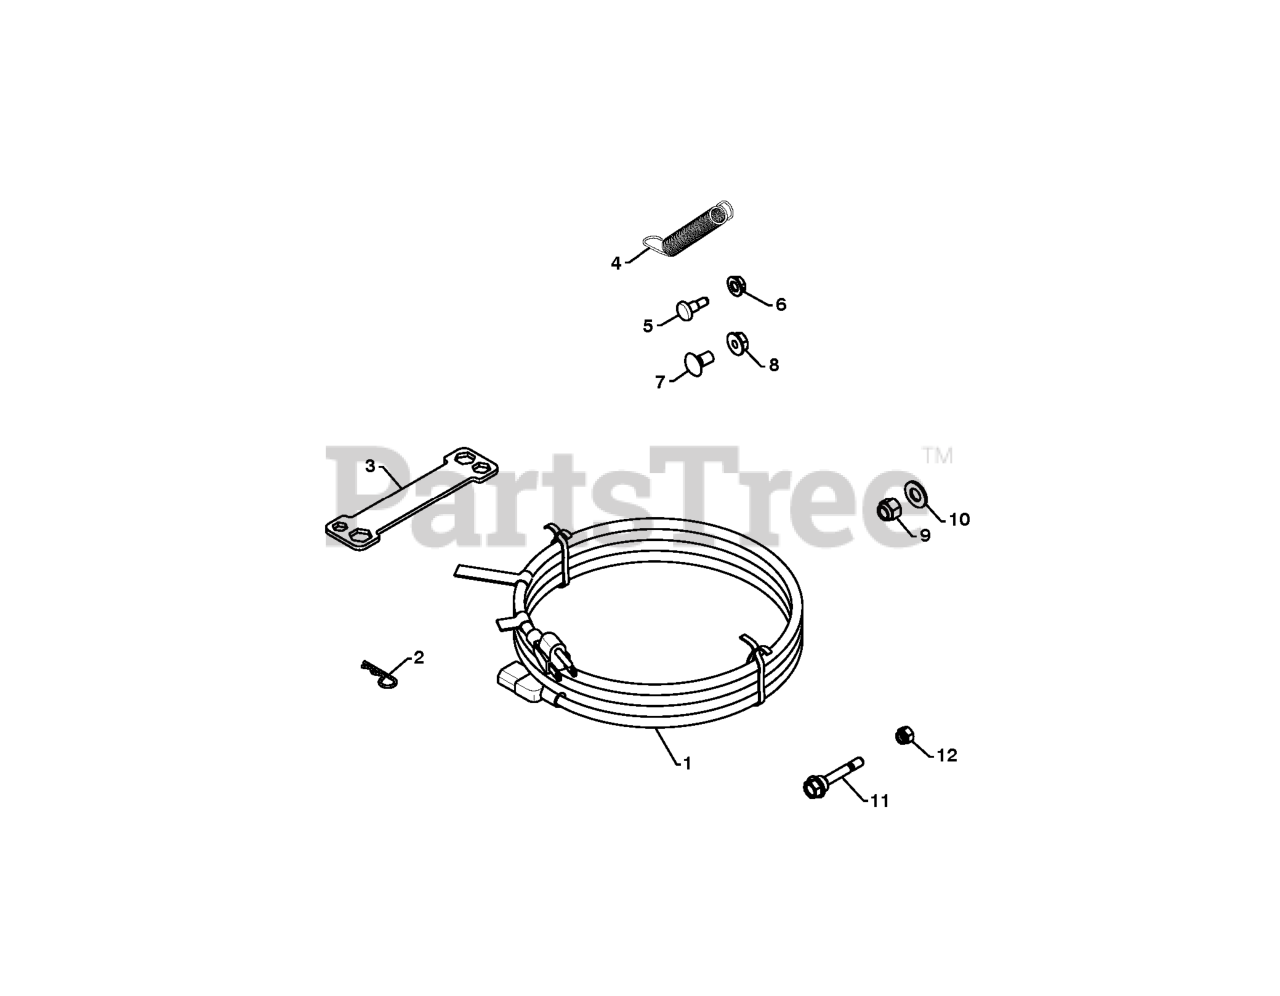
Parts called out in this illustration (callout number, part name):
1	CORD.ELECTRIC.10FT.120V.SNOW
2	SPRING RETAINER
3	RP WRENCH, SNOWTHROWER
4	SPRING.DEFLECTOR.REM.CHUTE
5	BOLT, SHOULDER
6	NUT.HEX.FLANGE.1/4
7	BOLT
8	NUT.LOCK.5/16-18
9	NUT
10	WASHER
11	BOLT.SHOULDER.SHEAR.1/4-20.
12	LOCKNUT.NYLOC.1/4-20
